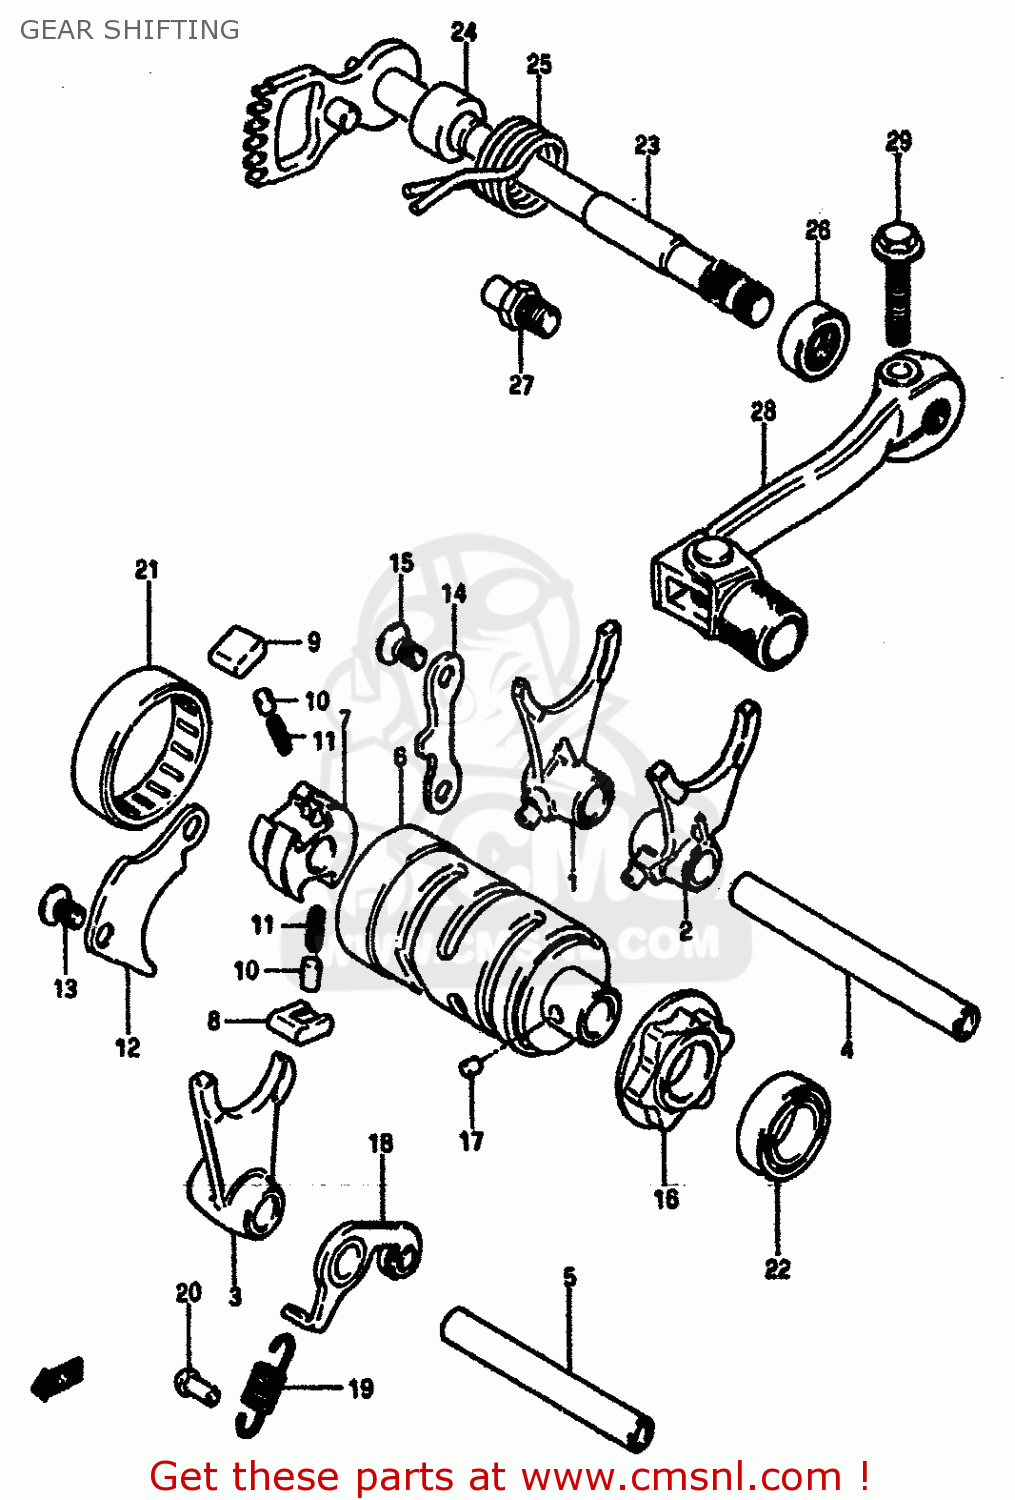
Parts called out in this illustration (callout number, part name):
1	FORK,GEAR SHIFT NO.1
2	FORK,GEAR SHIFT NO.2
3	FORK,GEAR SHIFT NO.2
4	SHAFT,GEAR SHIFT FORK
5	SHAFT,GEAR SHIFT FORK
6	CAM,GEAR SHIFT
7	GEAR,GEARSHIFT CAM DRIVE
8	PAWL,GEAR SHIFT NO.1
9	PAWL,GEAR SHIFT NO.2
10	PIN(5X8)
11	SPRING
12	LIFTER,GEAR SHIFT PAWL
13	SCREW
14	GUIDE,GEAR SHIFT CAM
15	SCREW
16	PLATE,GEAR SHIFT CAM STOPPER
17	PIN
18	STOPPER,GEAR SHIFTING
19	SPRING
20	RIVET
21	BEARING
22	BEARING
23	SHAFT,GEAR SHIFT
24	SPACER(12X20X15.3)
25	SPRING
26	OIL SEAL
27	STOPPER,GEAR SHIFT CAM
28	LEVER ASSY,GEAR SHIFT
29	BOLT
